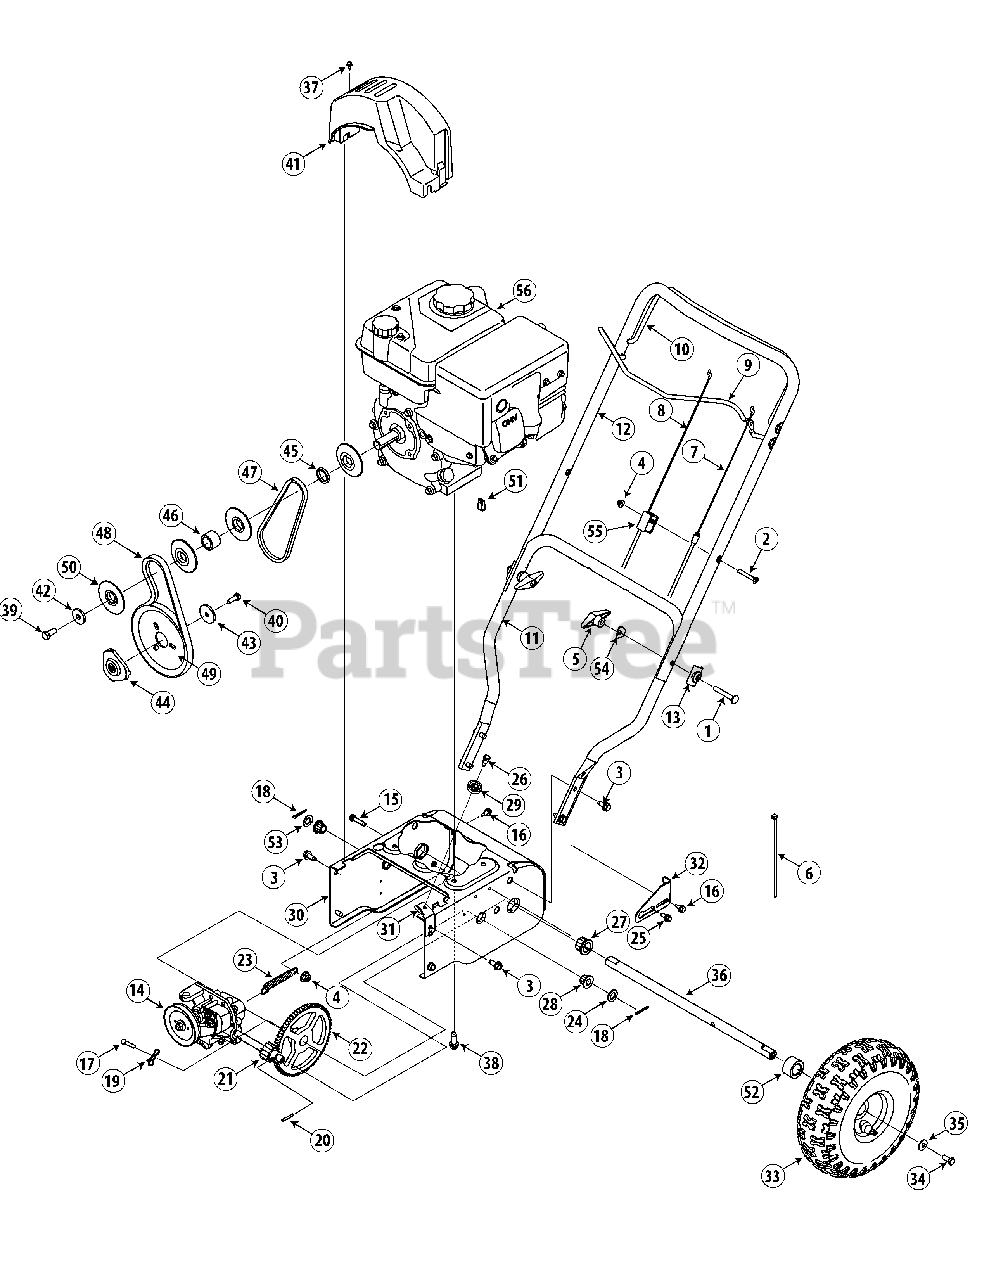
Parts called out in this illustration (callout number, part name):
1	Carriage Screw 5/16-18 x 2.25
2	Mach. Screw 1/4-20 x 1.825
3	Screw 5/16-18 x .75
4	Flange Lock Nut 1/4-20
5	Wing Knob 5/16-18
6	Cable Tie
7	Drive Cable
8	Auger Cable
9	Auger Control
10	Drive Control
12	Upper Handle
13	Handle Tab
14	Transmission Assembly
15	TT Screw 1/4-20 x 1.25
16	Screw 1/4-20 x .625
17	Clevis Pin
18	Cotter Pin 1/8 x 1.0
19	Bow Tie Cotter Pin 72
20	Roll Pin
21	Pinion 14T
22	Gear 70T
23	Extension Spring
24	Flat Washer
25	Shoulder Screw 1/4-20
26	Shoulder Screw 1/4-28
27	Hex Flange Bearing
28	Hex Flange Bearing
29	Cable Roller
30	Drive Housing Frame
31	Auger Cable Bracket
33	Wheel Assy Snow Hog Gray
33	Tube, Tire, 4.10/3.50-4.0
34	Lock Bolt 5/16-24 x .75
35	Bell Washer .34 x .872 x .06
37	Hex Screw #10-16 x .500
38	TT Sems Screw 3/8-16 x 1.0
39	Hex Bolt 3/8-24 x .875
40	Lock Bolt 5/16-24 x .875
41	Belt Cover
42	Flat Washer .406 ID x 1.25 OD
43	Flat Washer .34 ID x 1.50 OD
44	Pulley: Adapter .75 Dia.
45	Spacer .876 x 1.25 x .19
46	Spacer .876 x 1.25 x .86
47	V-Belt 3/8 x 21.108 Lg.
48	V-Belt 3/8 x 26.375 Lg.
49	Auger Pulley
50	Pulley Half
51	Amp Sealed Connector
53	Flat Washer .53 x .93 x .05
54	Saddle Washer
55	Cable Clip
